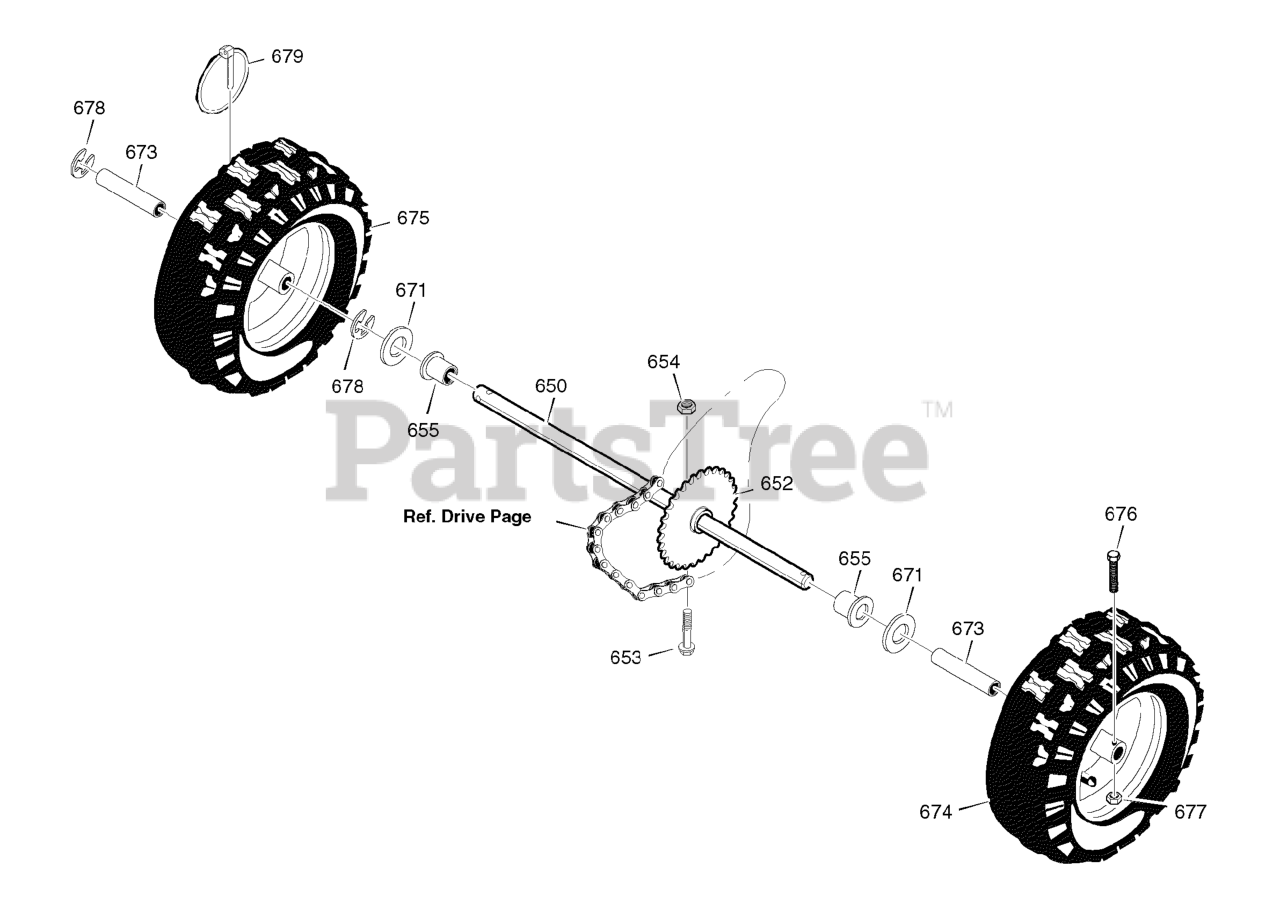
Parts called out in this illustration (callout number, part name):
650	SHAFT, Axle
652	SPROCKET & HUB
653	SCREW, 1/4-20 x 1-3/4
654	NUT, Hex Nylock, 1/4-20
655	BEARING, Axle
671	FLATWASHER
673	BUSHING, Wheel
674	TIRE & RIM, LH
675	TIRE & RIM, RH
676	SCREW, 1/4-20 x 1-3/4
677	NUT, Hex Nylock, 1/4-20
678	RING, Retainer
679	PIN, Klik
